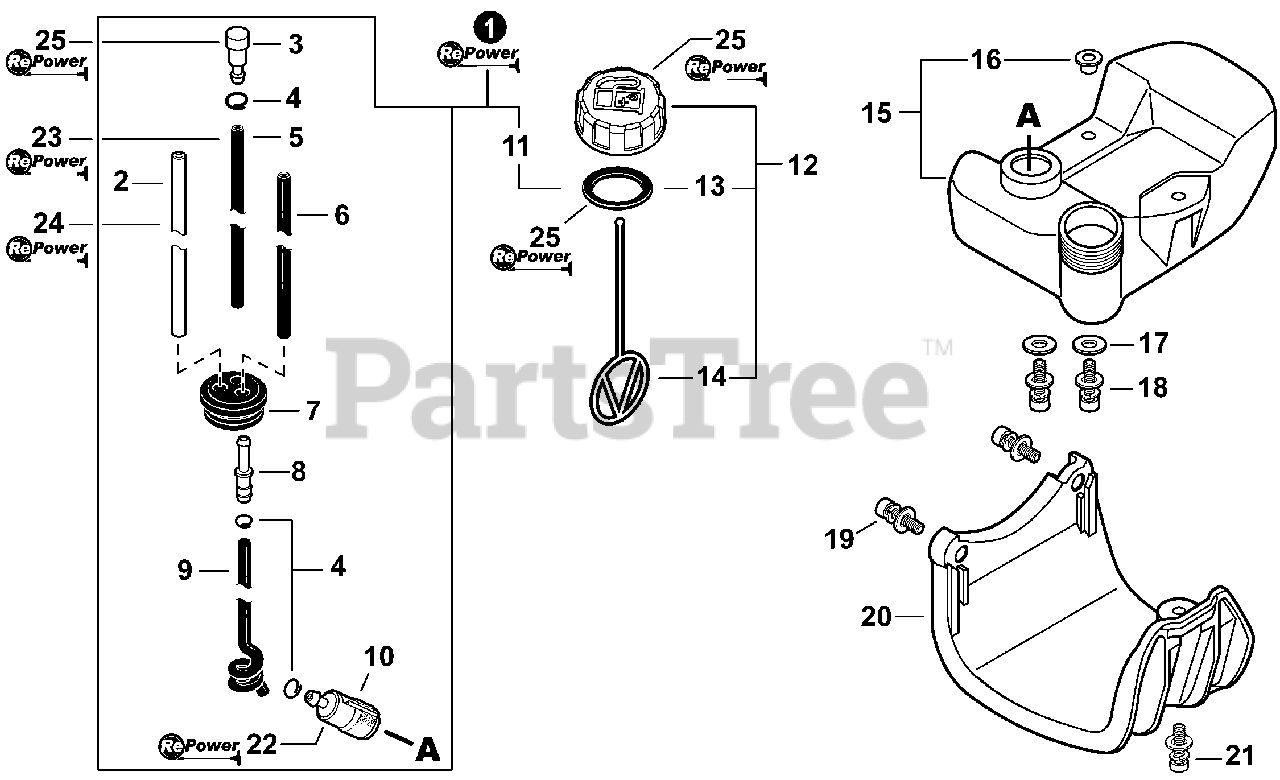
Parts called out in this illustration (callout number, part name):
1	FUEL SYSTEM KIT - REPOWER
2	PIPE, FUEL 3×6×80 CLEAR
3	VENT ASSY
4	CLIP Ø6.5MM
5	PIPE, FUEL 3×6×115 BLACK
6	PIPE, FUEL 3×5×74 BLACK
7	GROMMET, FUEL
8	CONNECTOR, PIPE Ø5ר3.5
9	PIPE, FUEL 3×6×105
10	FILTER, FUEL
11	GASKET, FUEL CAP
12	CAP ASSY, FUEL
13	GASKET, FUEL CAP
14	CONNECTOR, CAP L= 100mm
15	TANK, FUEL
16	COLLAR 5
17	WASHER 5.5×12×0.8
18	BOLT 5×16
19	BOLT 5×22
20	GUARD, FUEL TANK
21	SCREW 5×20
22	TUNE-UP KIT - REPOWER
23	PIPE, BULK - 3×6mm BLACK
24	PIPE, BULK - 3×6mm CLEAR
25	CAP/VENT KIT - REPOWER
